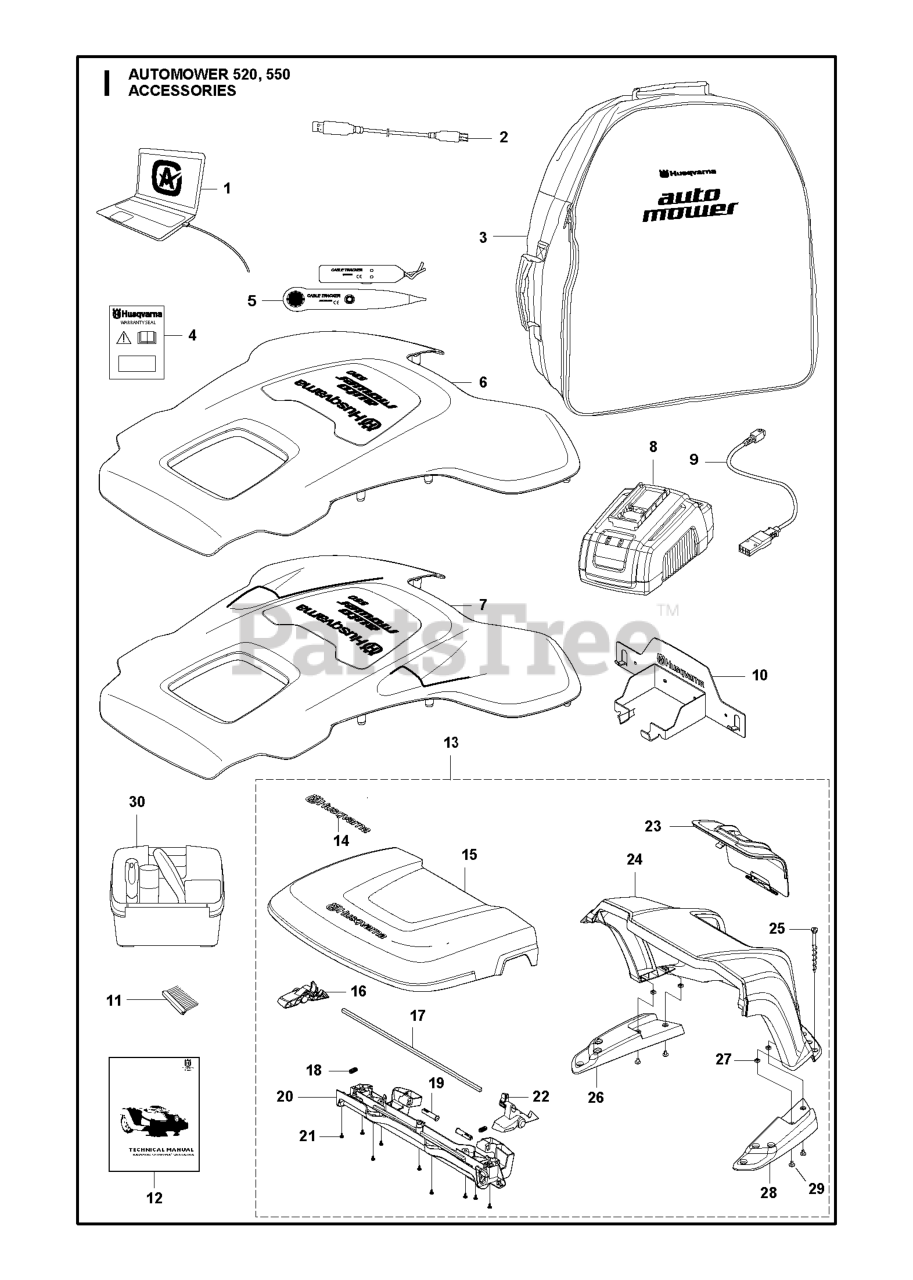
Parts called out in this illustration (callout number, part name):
2	CABLE WHITE ALT GREY
3	BAG
4	LABEL WARRANTY SEAL DEALER
5	TEST EQUIPMENT
8	CHARGER BATTERY TEST
9	CABLE ASSY QUICK CHARGER
10	MISC. BLISTER WALL HANGER
11	WHEEL BRUSH REFILL KIT
13	430/450 HOUSE KIT
14	DECAL.HUSQVARNA.210MM
15	KIT LID - AUTOMOWER HOUSE
16	HANDLE RELEASE LEFT
17	ROD
18	SPRING SPRING CAP
19	HINGE PIN
20	BEAM
21	SCREW 14MM
22	HANDLE RELEASE RIGHT
23	HATCH
24	COVER BASE P2 HOUSE
25	SCREW KIT CS
26	SUPPORT BASE LEFT
27	NUT
28	SUPPORT BASE RIGHT
29	SCREW IHPANM M6X25 4.6 ZP-BC
30	CLEANING AND MAITENANCE KIT AM
